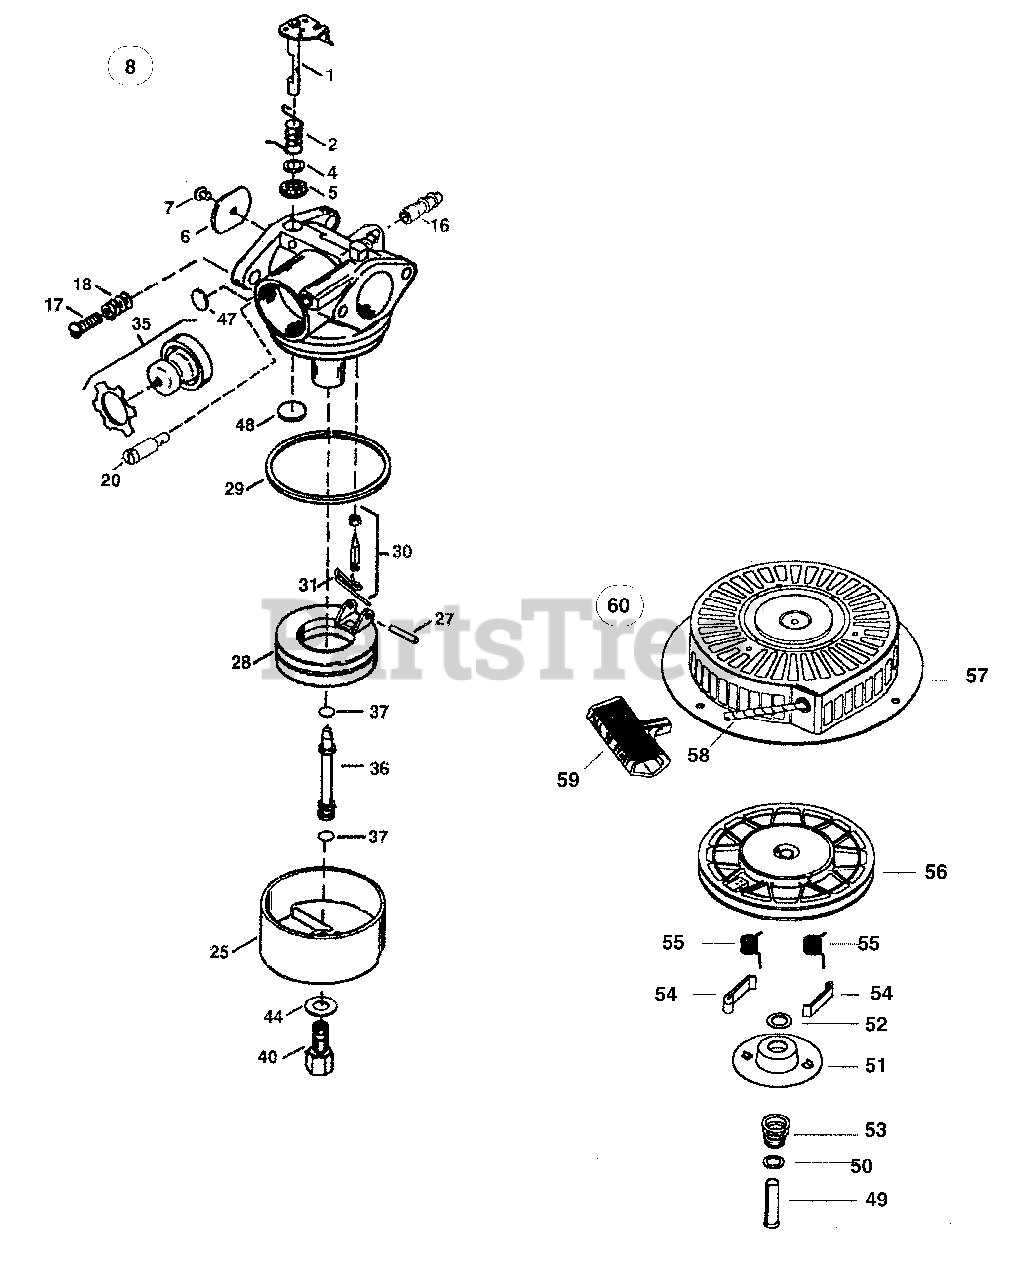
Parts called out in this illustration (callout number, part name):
1	Throttle Shaft & Lever Ass'y
2	Throttle Return Spring
4	Dust Seal Washer
5	Dust Seal (Throttle)
6	Throttle Shutter
7	Shutter Screw
8	Carburetor Assembly
16	Fuel Fitting
17	Throttle Crack/Idle Speed Screw
18	Tension Spring
20	Idle Restrictor Screw
25	Float Bowl
27	Float Shaft
28	Float
29	Float Bowl "O" Ring
30	Inlet Needle, Seat & Clip
31	Spring Clip
35	Primer Bulb/Retainer Ring
36	Main Nozzle Tube
37	Main Nozzle Tube "O" Ring
40	High Speed Bowl Nut
44	Bowl Nut Washer
47	Welch Plug, Idle Mixture Well
48	Welch Plug, Atmospheric Vent
49	Spring Pin,
53	Brake Spring
54	Starter Dog
55	Dog Spring
56	Pulley & Rewind Spring Ass'y
57	Starter Housing Ass'y
58	Starter Rope (98")
59	Starter Handle
60	Rewind Starter Ass'y
